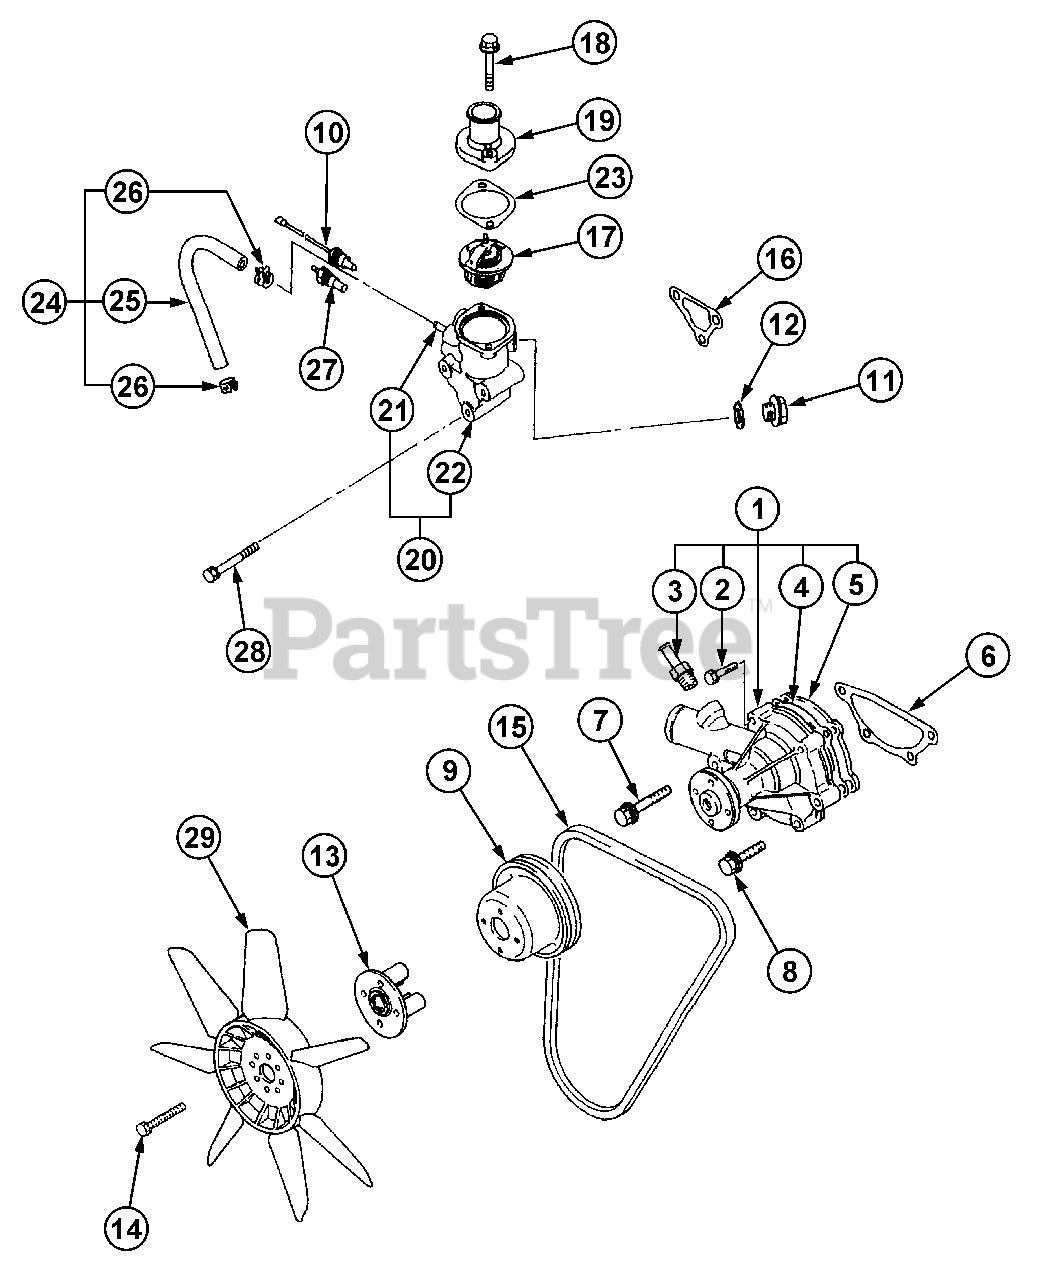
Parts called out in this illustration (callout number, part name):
1	Pump Assy, Water
2	Bolt, w/Washer
6	Gasket, Water
7	Bolt, w/Washer
8	Bolt, w/Washer
9	Pulley, w/Pump
11	Plug, Drain
14	Bolt, w/Washer
16	Gasket, Thermostat
18	Bolt, Flange
19	Cover, Thermostat
20	Case Assy, Thermostat
21	Pipe, Thermostat
22	Case, Thermostat
23	Gasket, Thermostat
24	Hose Assy, Fuel
25	Hose, Fuel
27	Unit, Water Temp
28	Bolt, w/Washer
29	Fan, Cooling
